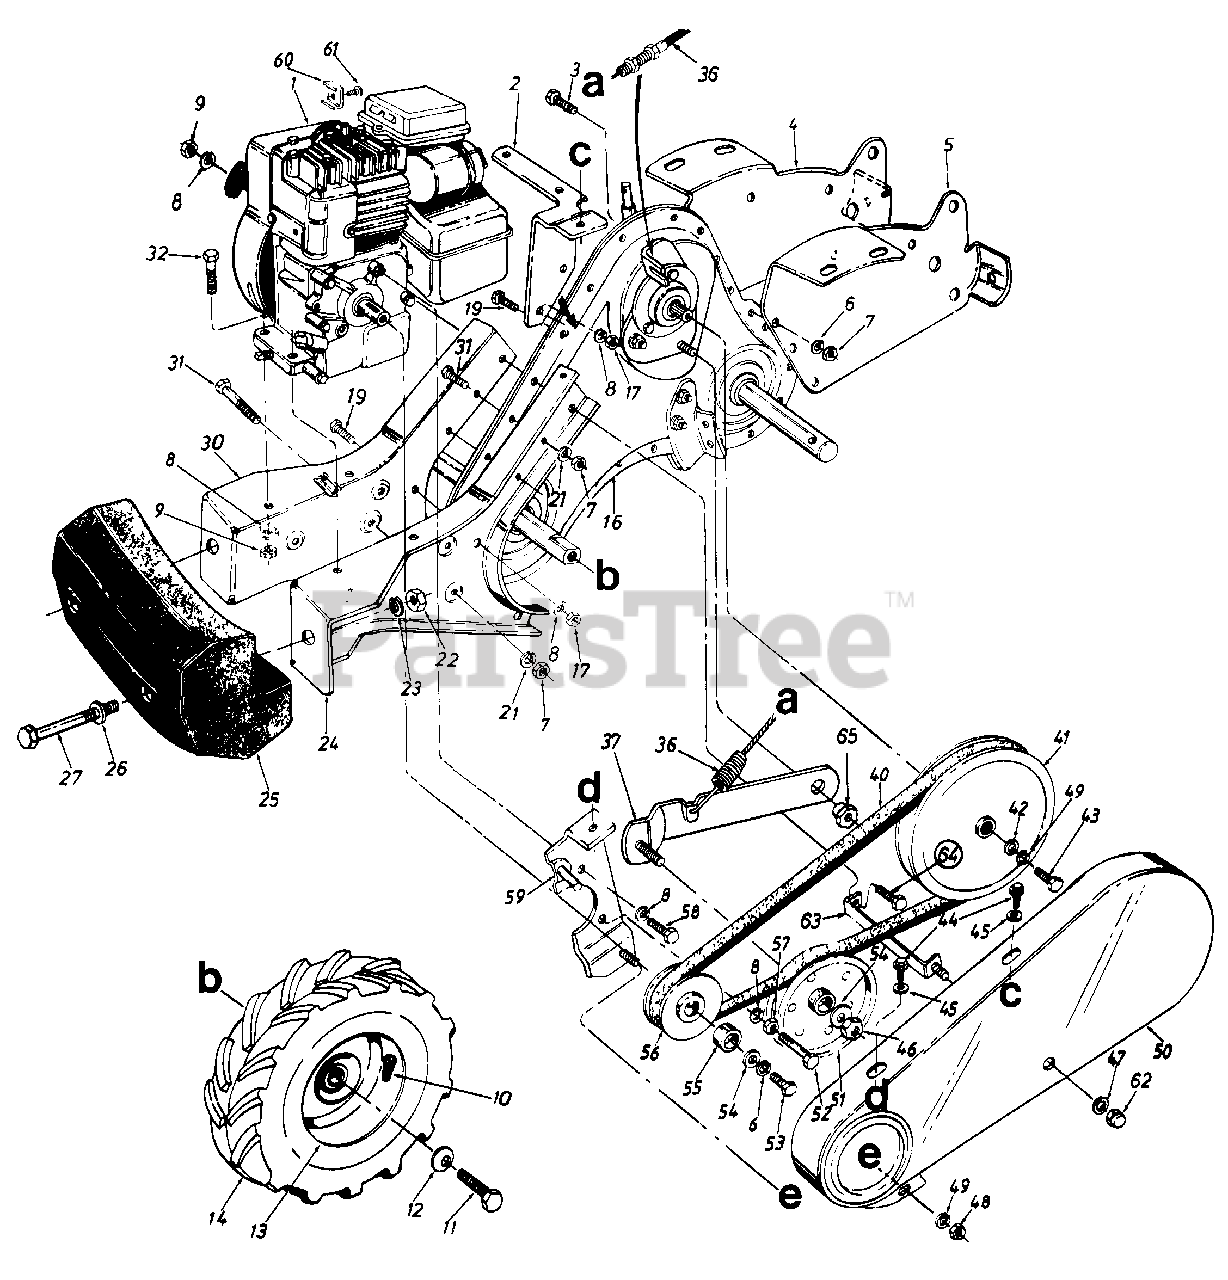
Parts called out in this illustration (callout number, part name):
1	Engine
7	Hex Nut 3/8-16 Thd.
8	L-Wash. 5/16" I.D.
9	Hex Nut 5/16-18" Thd.
10	Air Valve
11	Hex Bolt 5/16-24 x .62" Lg.
12	Bell-Wash. .345" I.D. x.88"
13	Wheel Rim Ass'y. Only
14	L.H. Wheel Ass'y. Comp.
17	Hex Nut 5/16-18 Thd.
19	Hex Bolt 5/16-18 x.75" Lg.
21	L-Wash. 3/8" I.D.-H.D.
22	Hex Nut 1/2-13 Thd.
23	L-Wash. 1/2" I.D.
26	Fl-Wash. .510" I.D. x 1.0"
27	Hex Bolt 1/2-13 x 5.00" Lg.
32	Hex Bolt 5/16-18 x 1.50"
36	Clutch Control Cable 46" Lg.
37	Idler Bracket Ass'y.
40	"V"-Belt
41	Fl-Pulley .8" O.D.
42	Fl-Wash. 1/4" I.D. x .93" O.D.
43	Hex Bolt 1/4-28 x .75" Lg.
44	Hex Wash. Hd. S-Tap Scr.1/4-20 x .50" Lg.
45	Fl-Wash. .281" I.D. x .625"
46	Hex Cent. L-Nut 3/8-24 Thd.
47	Fl-Wash. .266" I.D. x.625" O.D.
48	Hex Nut 1/4-20 Thd.
49	L-Wash. 1/4" I.D.
51	Fl-Idler w/Flanges 3.75" O.D.
52	Hex Bolt 5/16-24 x 1.75"
53	Hex Bolt 3/8-24 x 1.00" Lg.
54	Fl-Wash. 3/8" I.D. x 1.00"
55	Spacer.758" I.D. x .990"
56	Engine Pulley
57	Hex Nut 5/16-24 Thd.
58	Hex Bolt 5/16-24 x .62" Lg.
61	Hex Sems Scr. #10-32 x.62"
62	Hex Cap Nut 1/4-28 Thd.
63	Belt Cover Bracket Ass'y.
65	Shld. Nut
